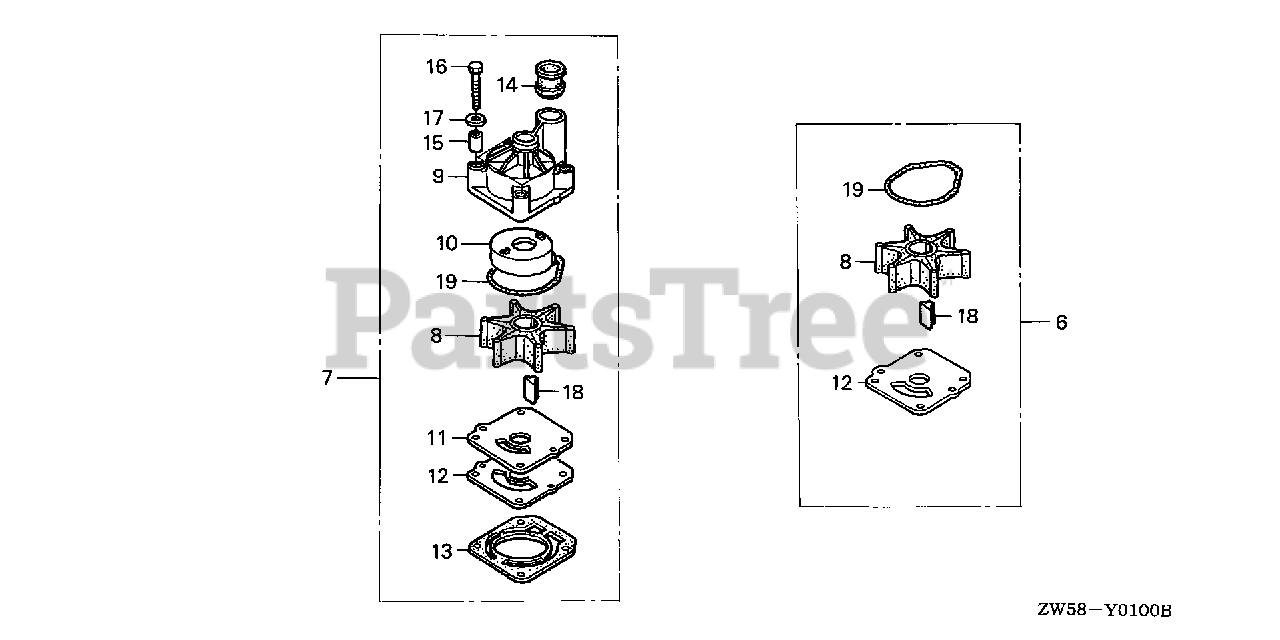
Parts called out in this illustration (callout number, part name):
6	PUMP KIT, IMPELLER
7	PUMP KIT, IMPELLER
8	IMPELLER, PUMP
9	HOUSING, IMPELLER
10	LINER, PUMP
11	COVER, IMPELLER
12	GASKET B, IMPELLER
13	GASKET, WATER PUMP
14	RING, WATER TUBE SEAL
15	COLLAR, DISTANCE
16	BOLT, HEX. (8X55)
17	WASHER (8MM)
18	KEY, WOODRUFF
19	O-RING, WATER PUMP
